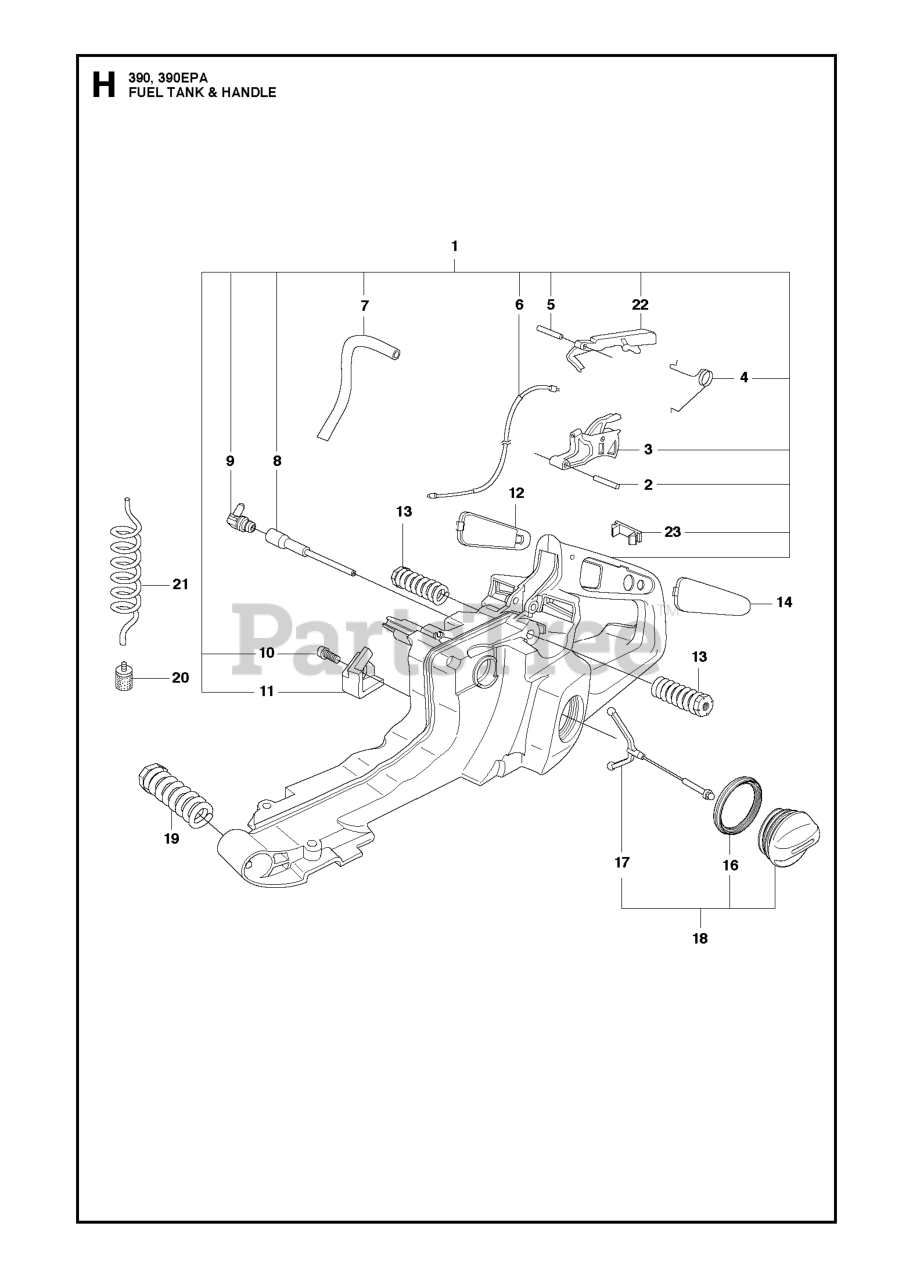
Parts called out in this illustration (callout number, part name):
2	PIN CPH8 4X20
3	THROTTLE TRIGGER
5	PIN 3X25
7	FUEL HOSE STRAIGHT 105
8	TANK VALVE
13	VIBRATION ABSORBER
19	VIBRATION ABSORBER
20	RP FUEL FILTER
21	FUEL HOSE SPIRAL 300
22	THROTTLE CATCH
